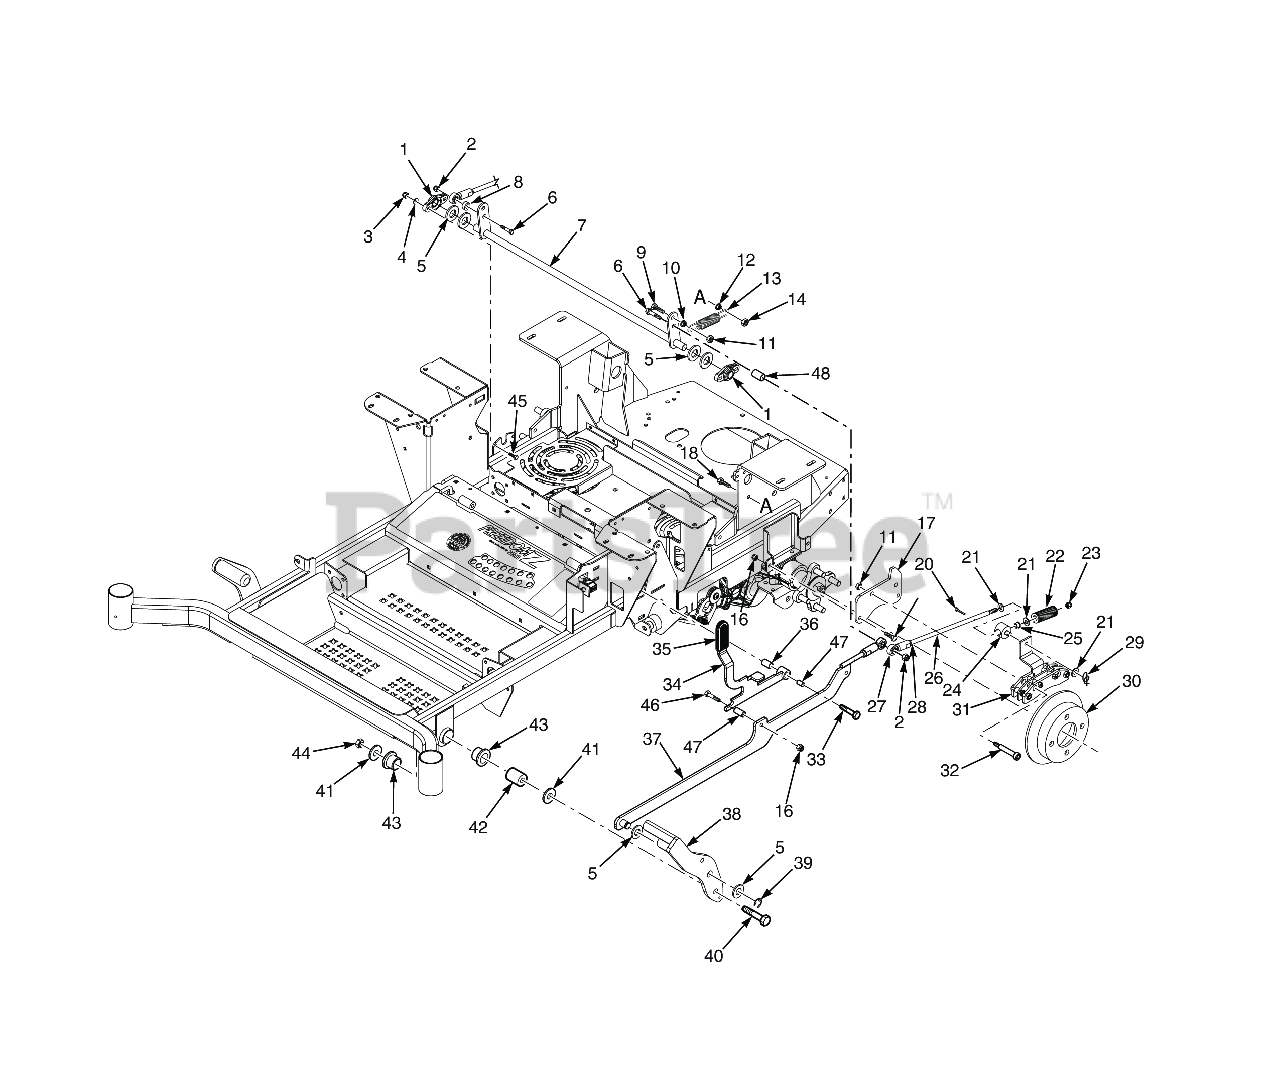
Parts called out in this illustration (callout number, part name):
1	Bearing
2	HEX NUT, ELASTIC STOP LOCK, 3/8-16
3	HEX, NUT, ELASTIC STOP LOCK, 1/4-20
4	Flatwasher, 1/4" (.312 x .750 x .065")
5	Flatwasher, 5/8" (.656 x 1.312 x .095")
6	Bolt, Hex Head 3/8-16 x 2-1/4" - 61"
7	Weldment, Brake Lever
8	Spacer, Idler Pulley - SFZ52
9	Bolt, Hex Head 3/8-16 x 1-1/4", Kawasaki FX / FS
10	NUT, 3/8-16 SERRATED FLANGE HEX HEAD
11	Bolt, Hex Head 3/8-16 x 1" Ser. Flg.
12	Nut, Serrated Flange 5/16-18 (Right Front Engine Mounting, Briggs and Kohler Only)
13	Spring, Deck Lift
14	Nut, Center Lock, 5/16-18(32)
15	Flatwasher, 3/8" Special (.391 x .938 x .105)
16	HEX NUT, ELASTIC STOP LOCK, 5/16-18
17	Mounting Bracket, Brake
18	Bolt, 5/16 - 18 x 1 - 1/4" Hex Head
19	Bolt, Heax Head 5/16-18 x 1" (48V / 52V)
20	Pin, Cotter 3/32 x .75"
21	Flatwasher, 3/8 (.406 x .812 x .065)
22	Spring, Brake
23	Nut, Elastic Stop 3/8-16, grade 8 black
24	Swivel Assembly, Brake
25	Bearing
26	Link, Brake
27	Rod End, 3/8-24 RH Female
28	Nut, 3/8-24 UNF R.H. Thread
29	Pin, Rue Cotter 3/8" Diameter
30	Spacer, Axle
31	Brake Caliper
32	Bolt, Shoulder 1/2 x 2-1/2"
33	Bolt, Shoulder 1/2 x 2"
34	Latch Assembly, Brake
35	Grip, Brake Handle
36	Bearing
37	Linkage Weldment Assembly, Brake
38	Brake Pedal Weldment
39	RETAINING RING, 5/8" EXTERNAL "E"
40	Bolt, Hex Head 1/2-13 x 3"
41	Flat Washer, 1/2 (.562 x 1.375 x .109)
42	Spacer, Deck Lift Pivot
43	Bearing, Plastic
44	Locknut, Hex 1/2-13 Center Lock
45	Capscrew, Hex Head 1/4-20 x 1"
46	Bolt, Hex Head 5/16-18 x 1-1/2" - Front
47	Sleeve, Handle Pivot
48	Spacer, Idler Pulley - SFZ61
